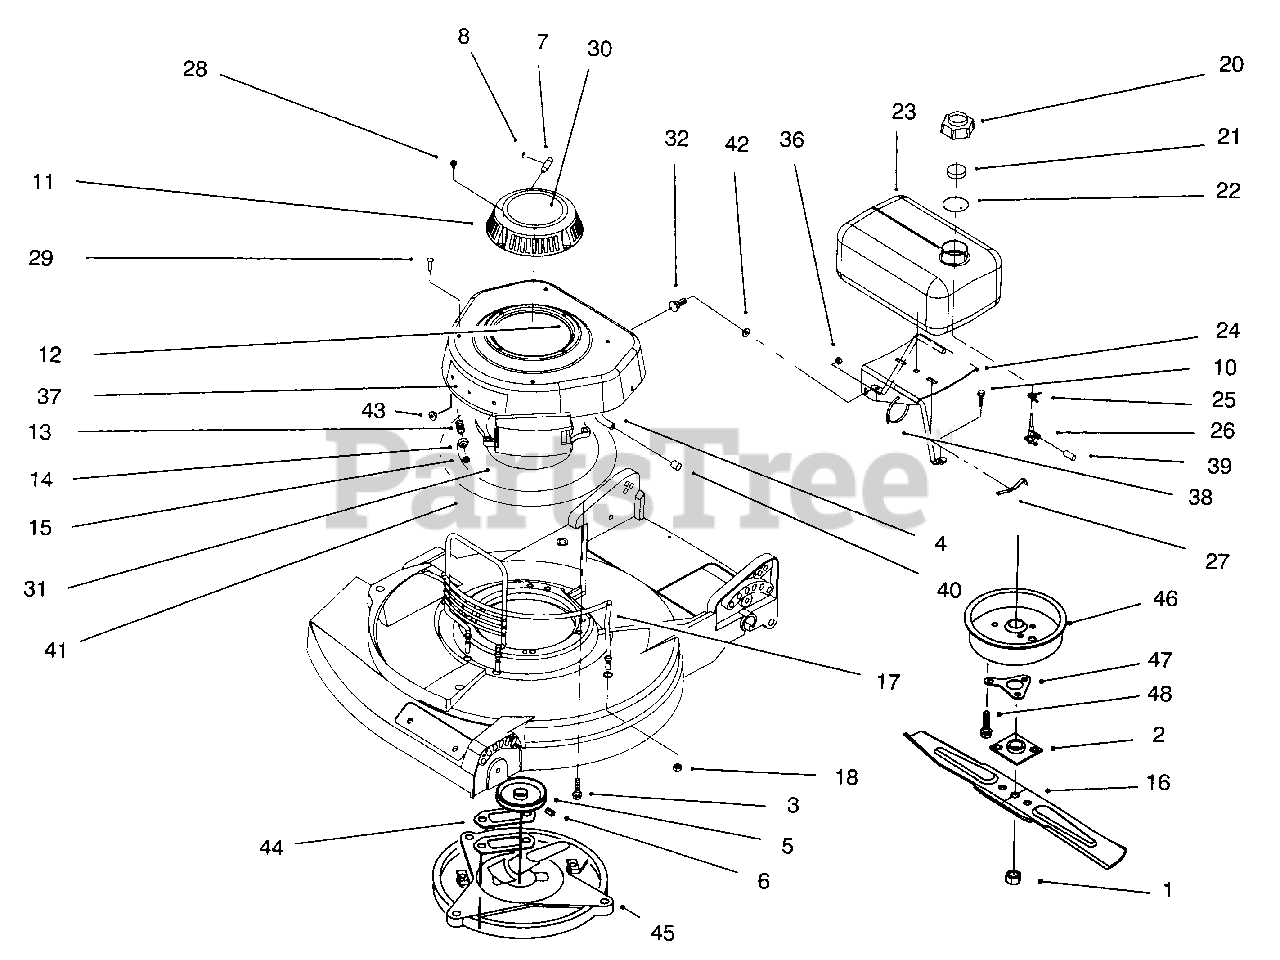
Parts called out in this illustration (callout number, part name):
1	Nut-Blade
2	Plate & Collar Assembly
3	Screw-Engine Mount
4	Hose-Gas
6	Screw-Set
7	Rope-Stop
8	Staple
10	Screw-Hex Washer Hd.
11	Housing-Starter
12	Shroud Assembly
14	Actuator-Brake Lever
15	Retainer
16	Blade-21"
17	Guard-Engine
18	Nut-Lock
20	Cap-Fuel
21	Foam-Baffle
23	Tank-Fuel
24	Leg & Saddle Assembly
25	Clamp-Hose
26	Valve & Screen
28	Screw-Sems
29	Screw-Thr'd Form
30	Decal-Recoil
31	Engine-2 Cycle
32	Screw-Carriage
36	Nut-Lock
37	Applique
38	Tie-Strap
39	Plug-Fuel Valve
40	Plug-Fuel Line
41	Plate-Engine
42	Washer-Flat
43	Retainer-Applique
44	Gasket-Muffler
45	Plate-Muffler
46	Muffler Cover Assembly
47	Support-Crankshaft
